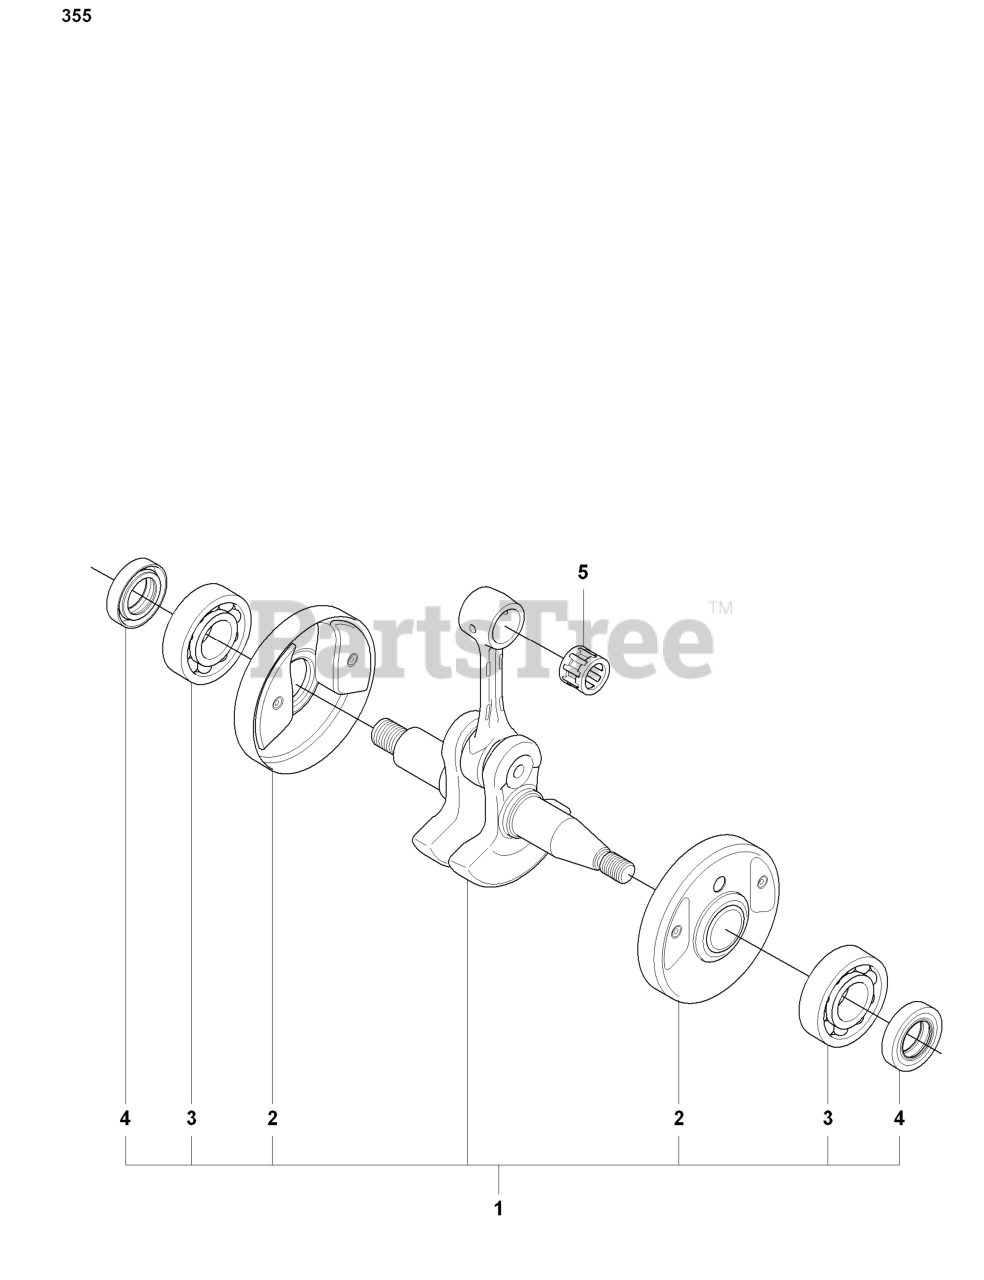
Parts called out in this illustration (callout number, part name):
1	CRANKSHAFT
3	BALL BEARING-6202-C3 SKF
4	SEALING RING
5	SUPPORT BUSHING
